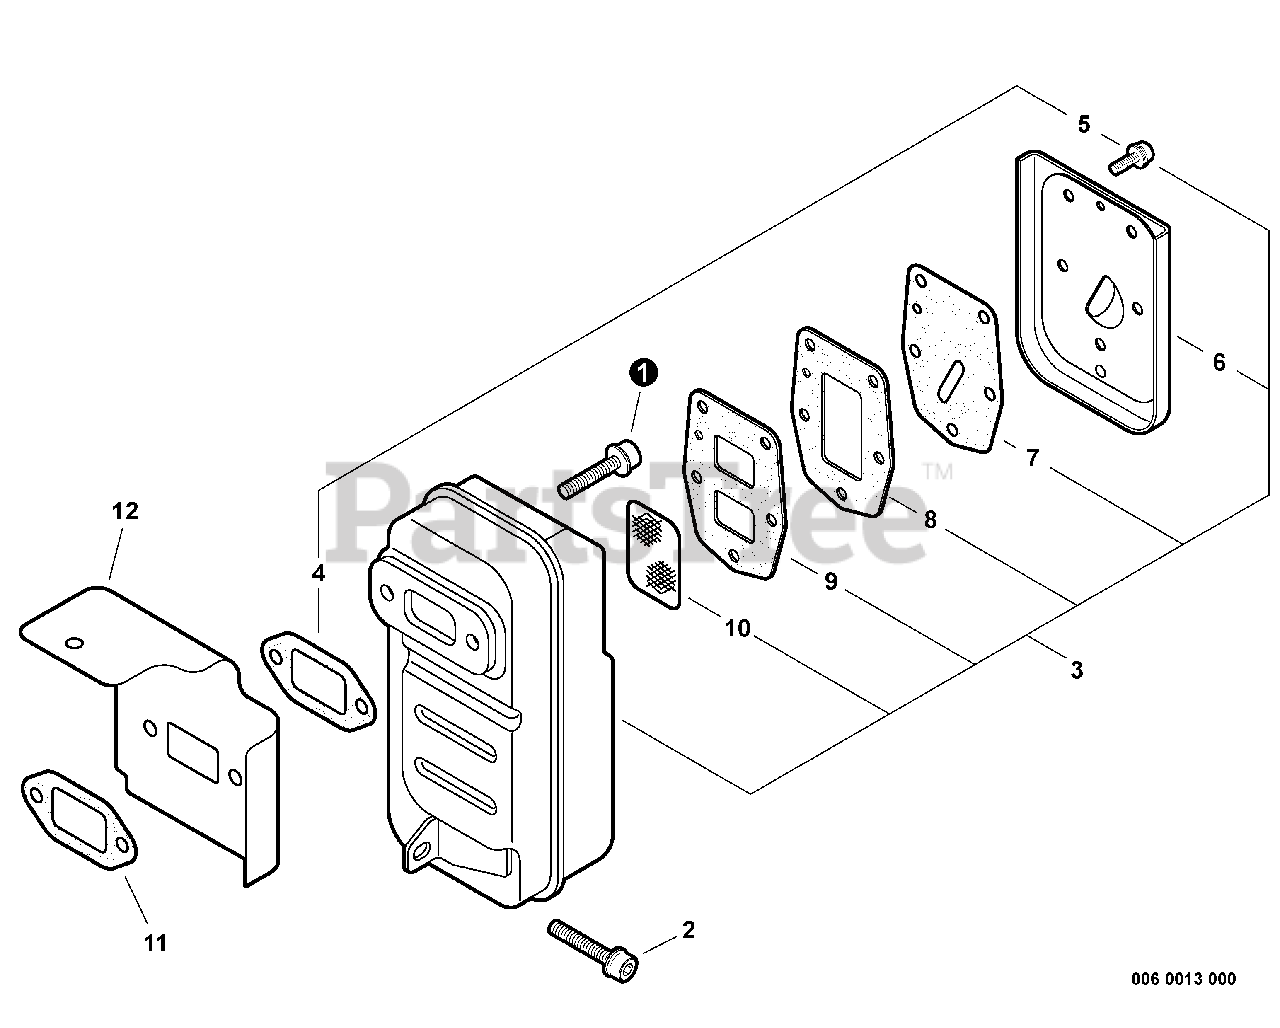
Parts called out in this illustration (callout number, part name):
1	SCREW - 6X20
2	SCREW - 5X20
3	MUFFLER ASSY
4	GASKET, EXHAUST
5	SCREW - 4X14
6	GUIDE, EXHAUST
7	GASKET, EXHAUST
8	GASKET, EXHAUST
9	GASKET, EXHAUST
10	SCREEN, SPARK ARRESTOR
11	GASKET, EXHAUST
12	COVER, CYLINDER - EXHAUST
